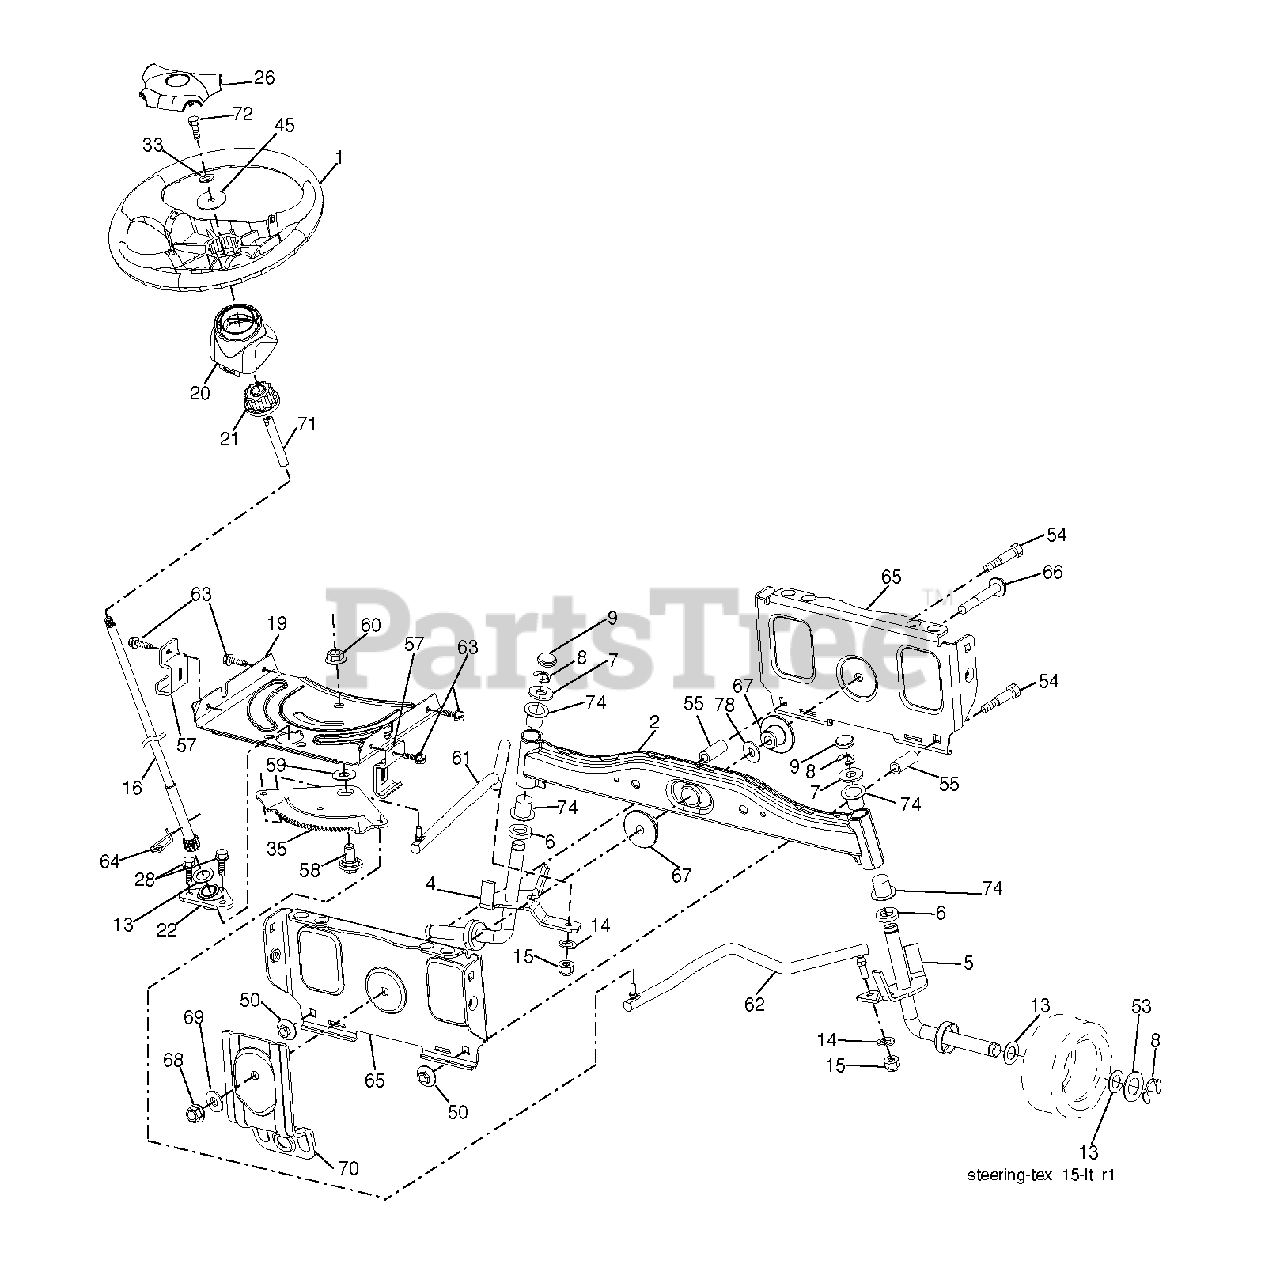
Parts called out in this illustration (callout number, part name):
1	WHEEL.STEERING.STDSRR.BLK/OV
2	AXLE HALF ASM-WELDED
4	SPINDLE.WELDED.LH.15"TEX
5	SPINDLE.WELDED.RH.15"T
8	RING CLIP
9	CAP.SPINDLE
14	WASHER, LOCK 3/8
15	NUT CROWNLOCK 3/8-24
16	SHAFT STEERING
19	PLATE.STEER.DDL.NLT/NG
20	BOOT.STEERING.PREDATOR.LT.BLAC
21	ADAPTER, WHEEL STNG..
22	BUSHING.ASM.STEERING.A
26	CAP.WHL.STRNG.STDSRRD.SRS.BLK
28	SCREW, 3/8-16X3/4
33	LOCKWASHER
35	GEAR.SECTOR.PLATE.DDL.
45	WASHER.11/32
50	NUT LOCK FLG 3/8-16 UNC
53	WASHER.HARDENED
55	SPACER.BRACE.AXLE
57	BRACKET.UPSTOP.TEX
58	BOLT.SHOULDER.SECTOR.P
59	WASHER.THURST.SECTOR.S
60	NUT FLANGE LOCK 5/8-11
61	DRAGLINK.LH.BALLSTUD.D
62	DRAGLINK.RH.BALLSTUD.D
63	SCREW
64	RETAINER.CLIP.SPRING.S
65	BRACE.AXLE.FRONT.NLT/N
66	BOLT HEX FGHD 7/16-14 X 3 SERR
67	BUSHING.PM.FRONT AXLE
68	NUT.LOCK.FLANGE.7/16
69	WASHER.1.5X.505X.118
70	BRKT.DECK.SUSPENSION.F
71	SHAFT EXTENSION STEERING
72	BOLT YT
74	BRNG T
78	THRUST WASHER
